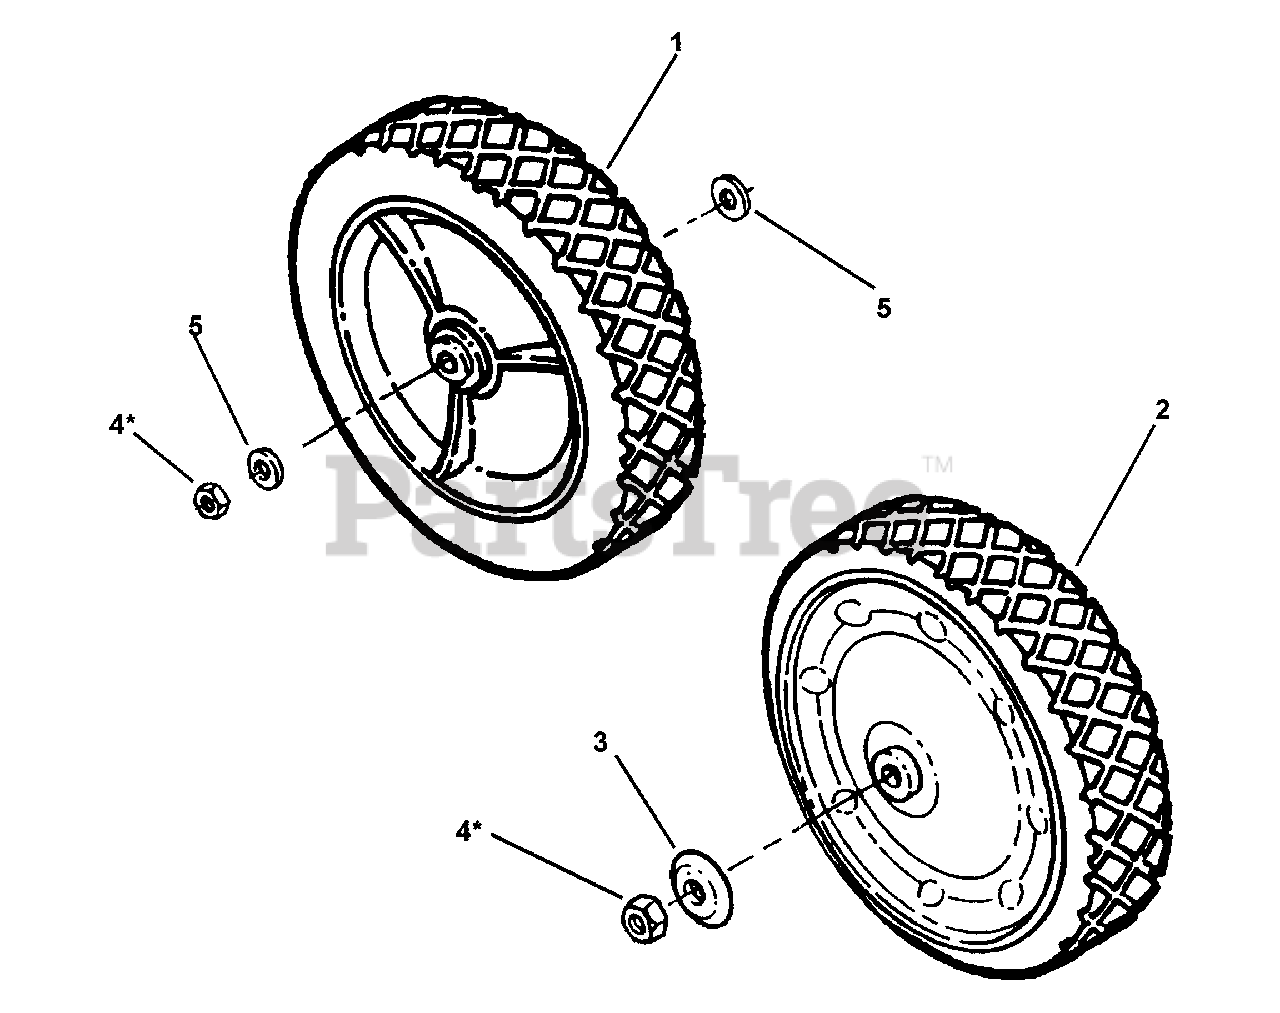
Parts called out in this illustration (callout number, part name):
1	WHEEL, 10 x 1.75 Plastic
2	WHEEL, 10 x 1.75
3	HUB-CAP
4	NUT, 7/16-20 Hex (Thin)
5	WASHER, 7/16 x 1" O.D. Flat
